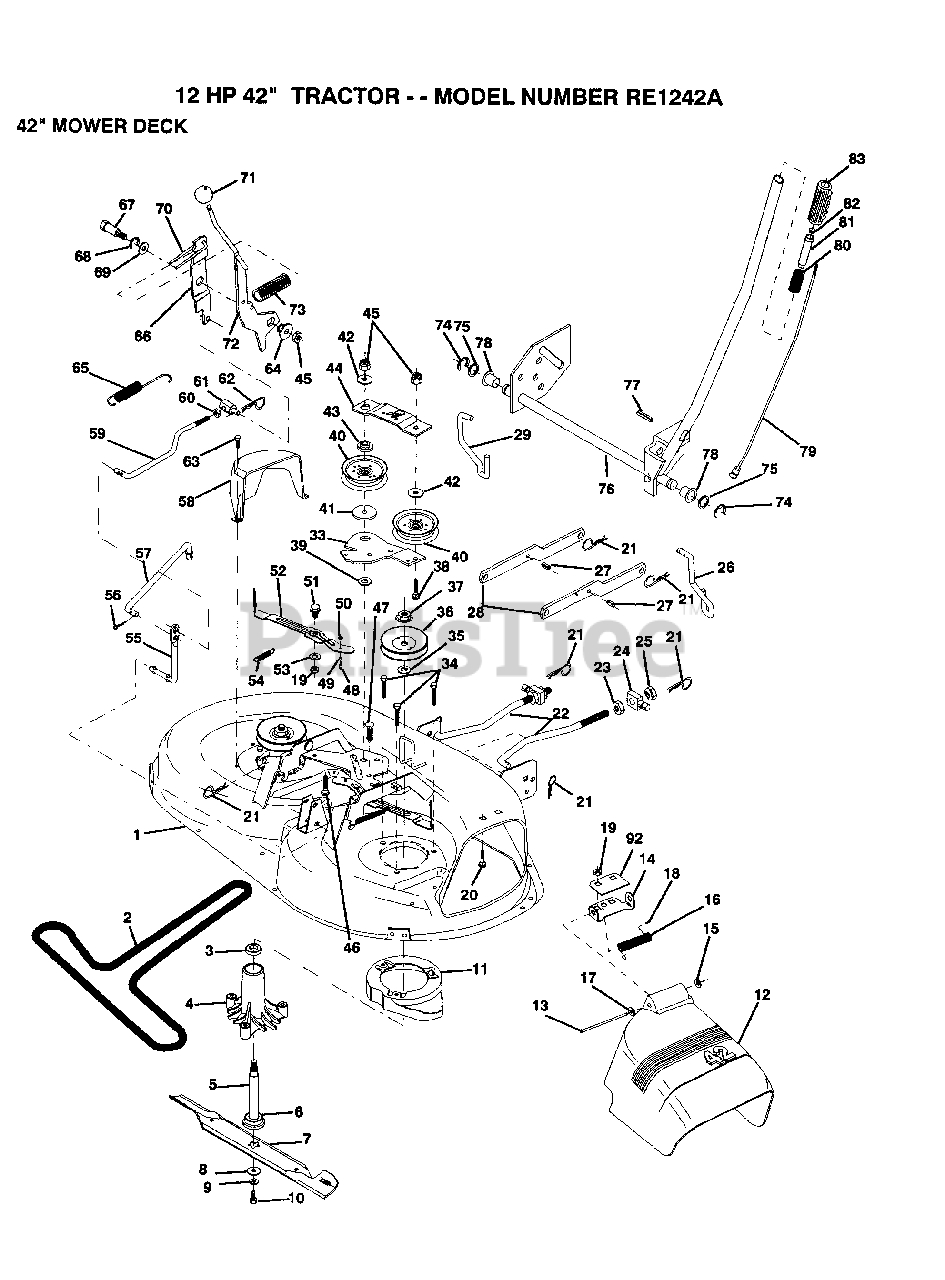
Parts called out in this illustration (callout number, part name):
2	BELT-V.92.4.MWR
3	BEARING
4	HSG ASM MANDREL
6	BEARING.BALL
8	WASHER BLADE
10	BLADE BOLT
12	DEFLECTOR.SHIELD
13	HINGE ROD
14	DEFLECTOR BRKT
15	NUT PUSH M
16	SPRING TORSION
17	WASHER
18	CAP-SLEEVE LT
20	BOLT
22	LINK.FRONT
23	NUT
24	TRUNION
25	NUT.LK.W/WSH.1/2.
26	LIFT LINK RH
27	"PIN,SPRING"
28	SUSP ARM ASM REAR
29	LINK LIFT LH
33	IDLER ARM
35	WASHER
38	BOLT
39	HARDENED WASHER
40	FLAT IDLER PULLEY
41	SPACER RETAINER
42	WASHER GT
43	RETAINER SPACER
44	IDLER ARM STIFF
46	BOLT CARRIAGE
47	XMAS TREE FASTNER
48	SHOULDER BOLT
50	LOCKNUT
52	BRAKE PAD ARM ASM
53	HARD SMALL WASHER
54	SPRING EXTENSION
55	PIVOT ROD
57	CLUTCH ROD SECOND
60	NUT
61	TRUNION
62	RETAINER M
63	SCREW LT
64	BUSHING
65	RETURN SPRING
66	CLUTCH ARM SECOND
67	SHOULDER BOLT
68	RING
69	WASHER
70	SPRING KEEPER
72	CLUTCH ARM PRI AS
75	WASHER
77	PIN-GROOVE LT
78	NYLON BEARING
83	GRIP
92	STIFFENER BRKT
